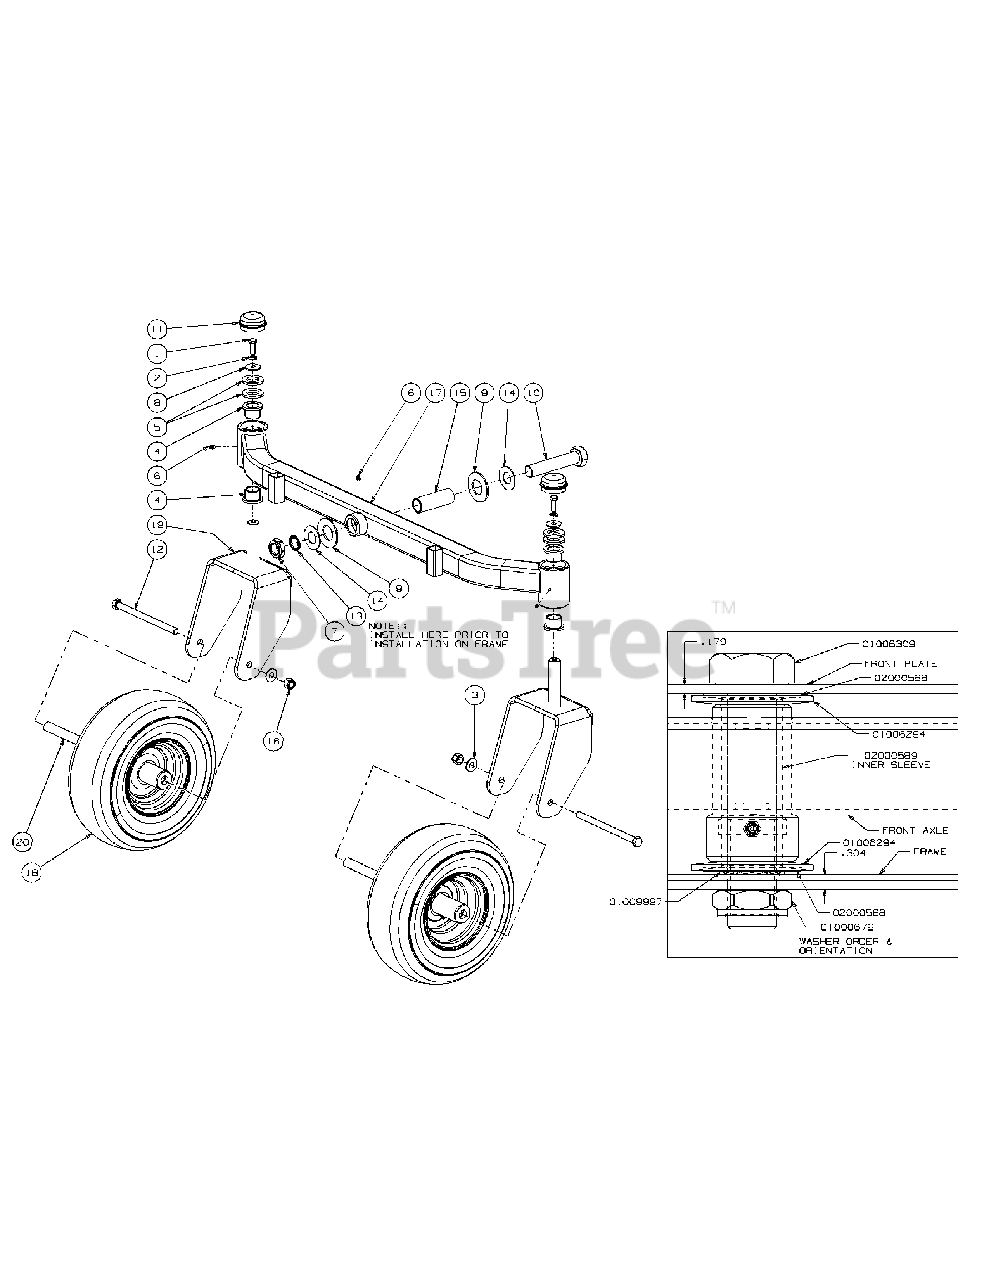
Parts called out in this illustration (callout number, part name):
1	Hex Cap Screw, 3/8-16 x 1.00
2	Lock Washer, 3/8
3	Washer, 1/2 x 1 Shim
4	Flange Bearing, 1.013 ID
5	Washer Special
6	Grease Fitting, 1/4-28 x 3/16
7	Nut, Jam, 1.0-14, Insert Lock
8	Flat Washer, 1.25 x .411 x .100
9	Bell Washer, 1.25 ID x 2.5 x .157
10	Hex Cap Screw, 1-14 x 5.0
11	Grease Cap, 1.986 OD
12	HHCS, 1/2-20, 7.50
13	Retainer Extension, Self Locking
14	Flat Washer, 1.00 ID
15	Spacer, 1.005 ID x 1.25 OD x 3.6
16	Lock Nut, Nylon Insert, 1/2-20
17	Front Axle Assembly
18	Wheel, 13 x 5.00 x 6.0, includes:
19	Castor Wheel Mounting Bracket
20	Spacer, .51 ID x .75 OD x 5.825
